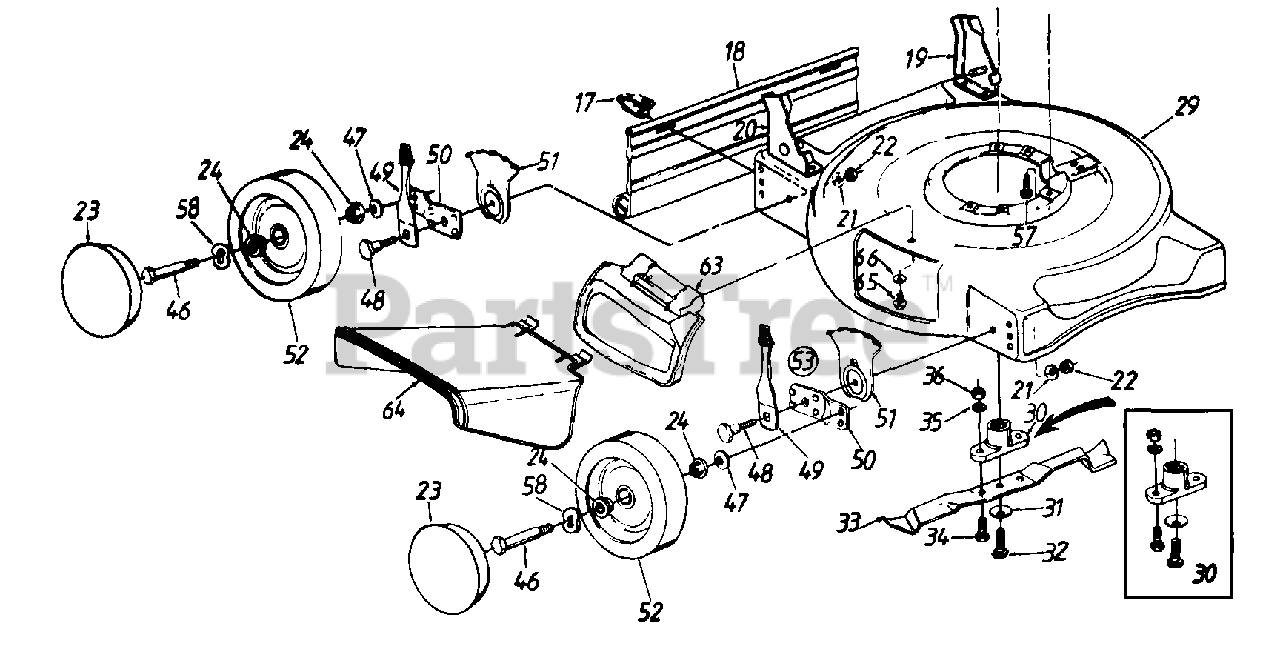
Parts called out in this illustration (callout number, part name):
17	Hinge Clip
18	Rear Flap (108R)
19	Handle Bracket Ass'y.- L.H. (108R)
20	Handle Bracket Ass'y.- R.H. (108R)
21	Bell-Wash..39" I.D. x 1.38"
22	Hex Nut 3/8-16 Thd.
23	Hub Cap
24	Bearing
29	20" Deck Ass'y. (108R)
31	Bell-Wash..46" I.D.
32	Hex Bolt 7/16-20 x 1.5" Lg.
33	20" Mulching Blade (108R)
34	Hex Bolt 3/8-24 x 1" Lg.
35	L-Wash. 3/8" I.D.
36	Hex Nut 3/8-24 Thd.
46	Axle Bolt
47	Bell-Wash..400" I.D. x.88"
48	Shld. Bolt .50" Dia. x .357"
49	Spring Lever Ass'y. w/Knob
51	Height Adj. Plate
52	Wheel Ass'y. Comp.
53	Height Adj. Ass'y. Comp.- R.F. & L.R.
57	Hex L-Wash. Hd. Scr. 3/8-16 x 1.0" Lg.
58	Wave Washer .51" I.D.
63	Mulching Plug (108R)
64	Chute Deflector
65	Bell-Wash. 1/4" I.D.
66	Hex Wash Hd. TT-Tap Scr. 1/4-20 x .5" Lg
